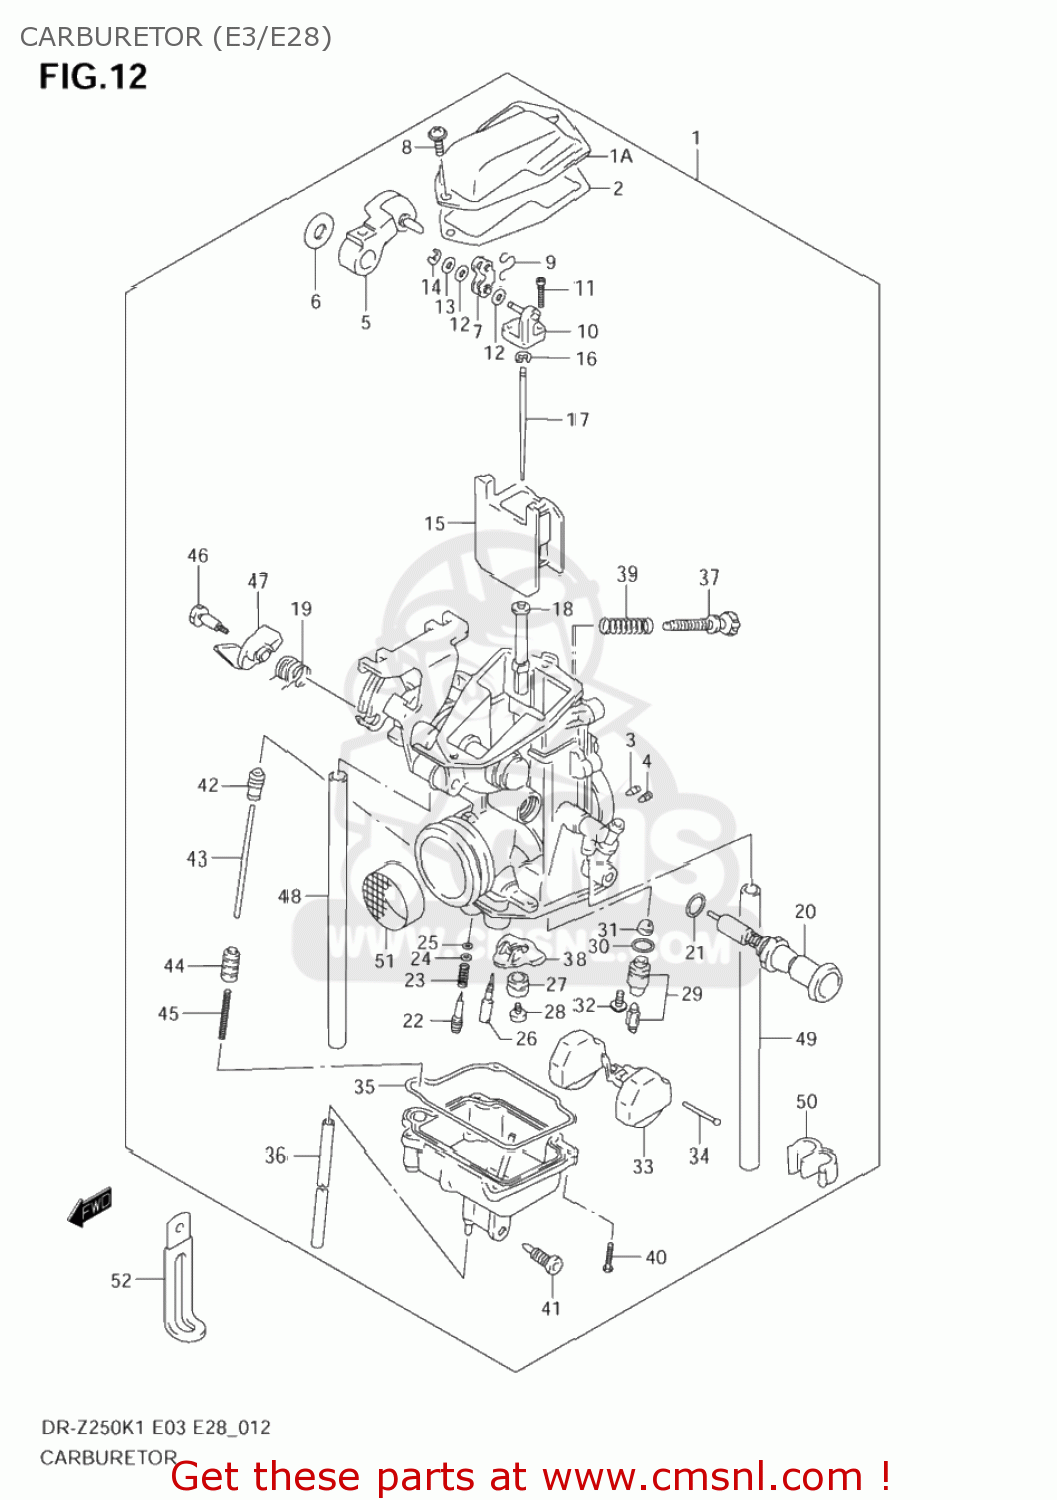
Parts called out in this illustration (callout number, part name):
1	CARBURETOR ASSY
1A	COVER,TOP
2	GASKET,CARBURETOR TOP (NAS)
3	JET,AIR(1.2)
4	JET,AIR(1.6)
5	LEVER SET,THROTTLE
6	WASHER
7	PLATE
8	SCREW
9	CLIP ASSY
10	CONNECTOR
11	SCREW
12	GASKET (NAS)
13	WASHER(4.5X8X0.5)
14	E RING
15	VALVE,PISTON
16	E RING
17	NEEDLE,JET(6FN3-3)
18	JET,NEEDLE(P-6M)
19	SPRING
20	PLUNGER ASSY
21	O RING
22	SCREW,PILOT
23	SPRING
24	WASHER
25	O RING,PILOT AIR SCREW
26	JET,PILOT(37.5)
27	RING,MAIN JET FIXING
28	JET,MAIN(127.5)
29	VALVE ASSY,NEEDLE
30	O RING,NEEDLE VALVE SEAT
31	FILTER
32	SCREW
33	FLOAT
34	PIN,FLOAT
35	O RING,FLOAT CHAMBER
36	HOSE(3X5X600)
37	ADJUSTER
38	RING
39	SPRING
40	SCREW
41	PLUG,DRAIN
42	BOOT, ACCELE PUMP ROD
43	ROD,PLUNGER
44	PLUNGER
45	SPRING
46	BOLT
47	LEVER
48	HOSE(5X9X600)
49	HOSE(5X9X600)
50	CLAMP
51	NET,INTAKE
52	CLAMP(L:65)
